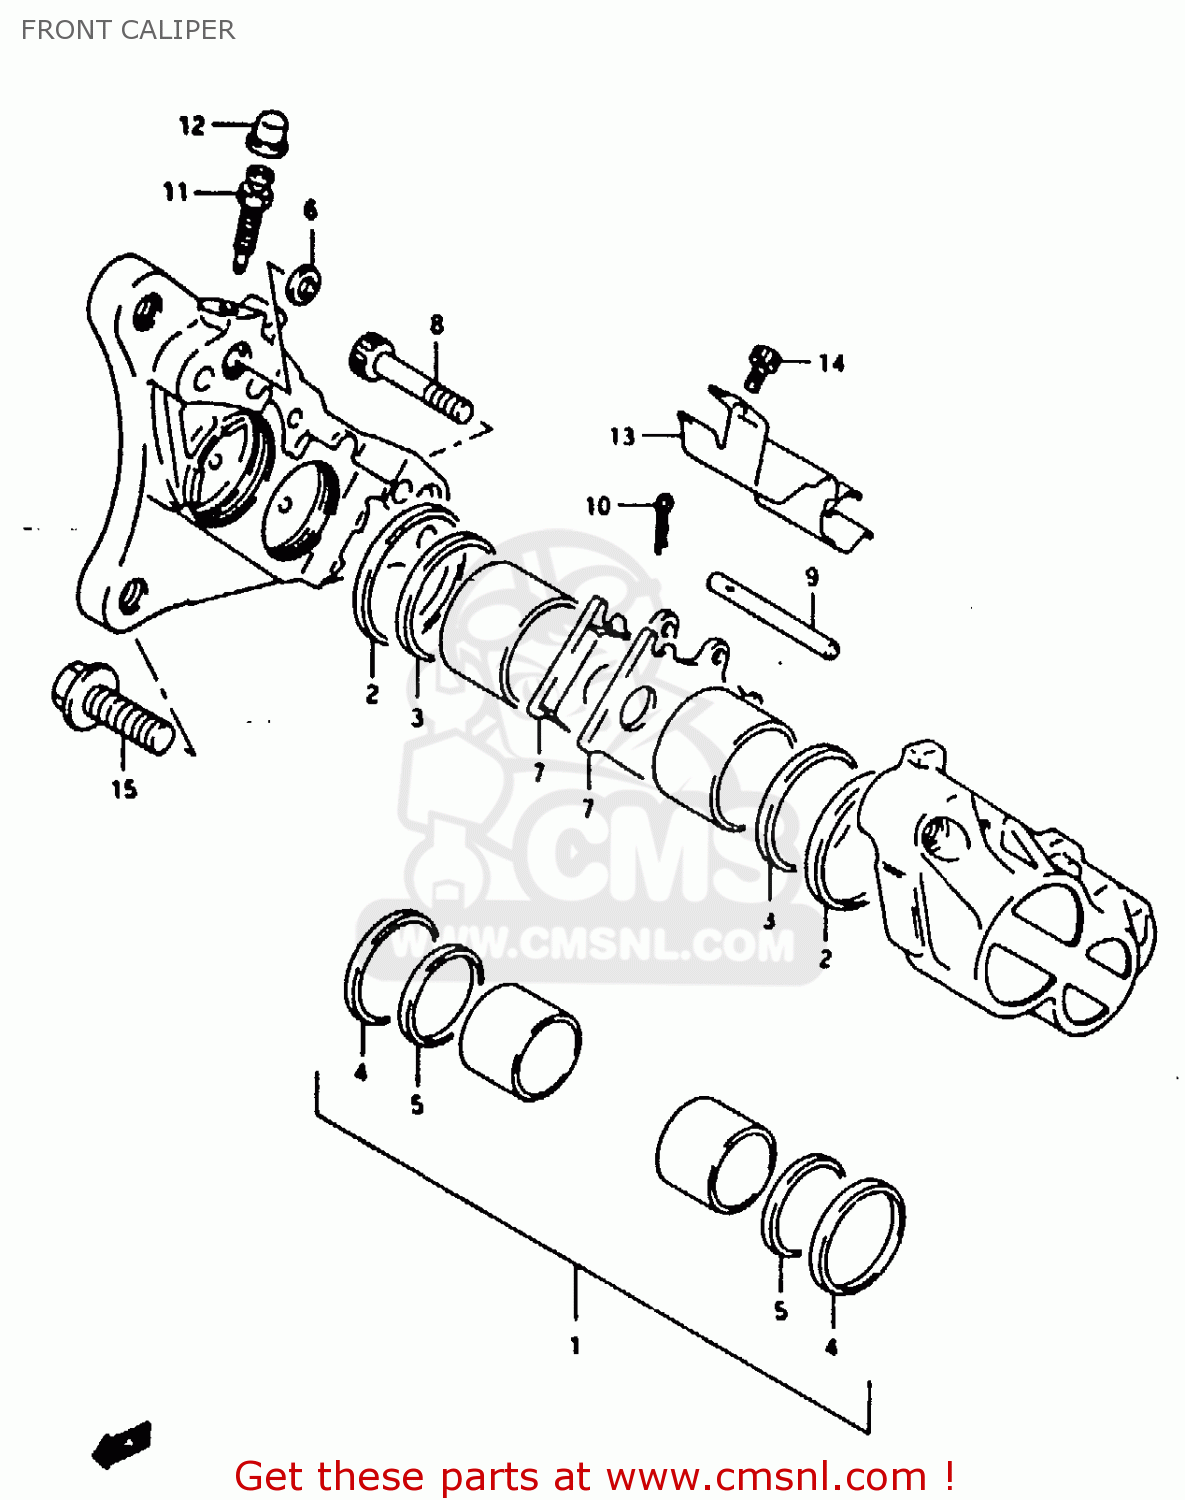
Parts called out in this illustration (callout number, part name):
1	PISTON SET,BRK
2	SEAL,PISTON
3	SEAL,WIPER
4	SEAL
5	SEAL,WIPER
6	SEAL,JOINT
7	PAD
8	BOLT,CALIPER
9	PIN,PAD
10	CLIP,PAD PIN
11	BLEEDER
12	CAP,BREATHER
13	COVER,DUST,R.
14	SCREW
15	BOLT
